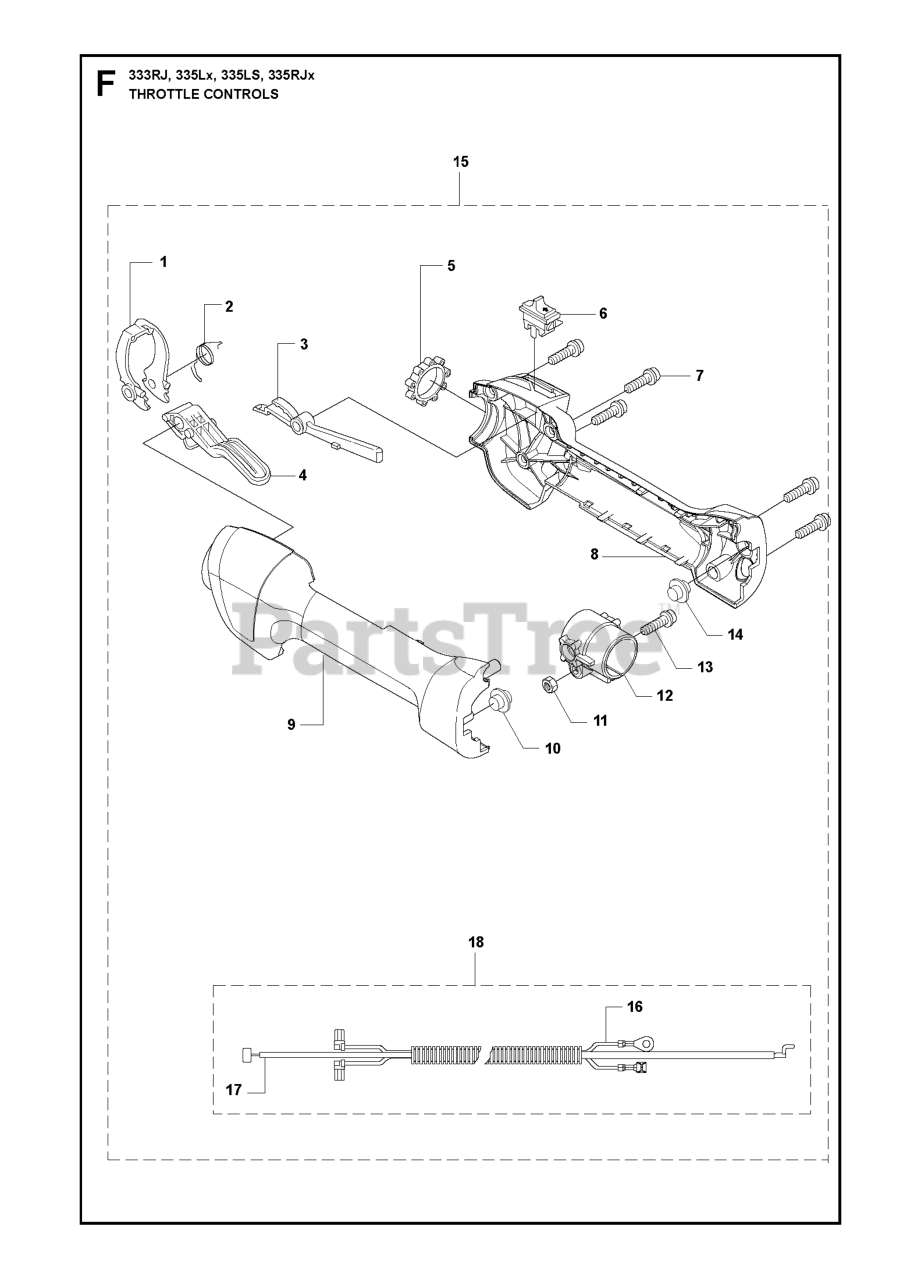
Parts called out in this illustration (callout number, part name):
2	RETURN SPRING
3	THROTTLE LOCK
4	THROTTLE TRIGGER
5	VIBRATION DAMPER
6	STOP BUTTON
8	HANDLE
9	HANDLE
10	VIBRATION ABSORBER
14	VIBRATION ABSORBER
15	THROTTLE HANDLE CPL
16	SHORT CIRCUIT CABLE
17	THROTTLE WIRE ASSY
18	WIRING ASSY.
